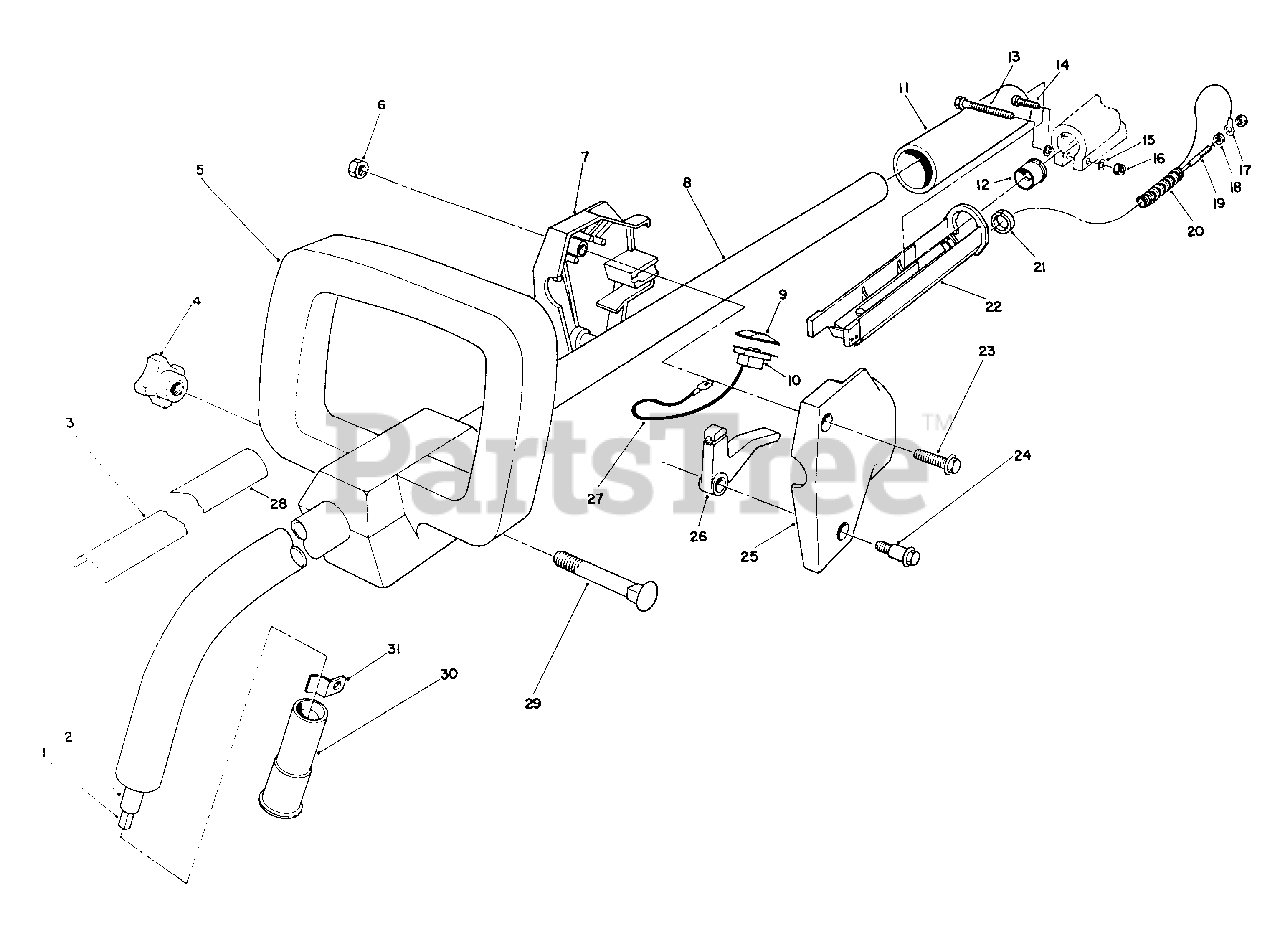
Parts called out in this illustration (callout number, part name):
1	Flex Shaft-Drive
2	Flex Shaft Liner
3	Decal-Model No.
4	Knob-Loop Handle
7	Housing-R.H.
8	Tube-Curved
9	Cap-Switch
12	Bushing-Pilot
13	Screw-Engine Clamp
14	Screw-Lock
15	Washer-Engine Clamp
16	Nut-Engine Clamp
17	Wire Assembly
18	Nut-Jam
19	Cable-Throttle
20	Cover-Cable
23	Hex Washer Hd. Screw
24	Screw-Shoulder
25	Housing-L.H.
26	Lever-Throttle
27	Wire Assembly
28	Decal-Warning
29	Bolt-Carriage
30	Insert-Pole End
31	Retainer-Tube
